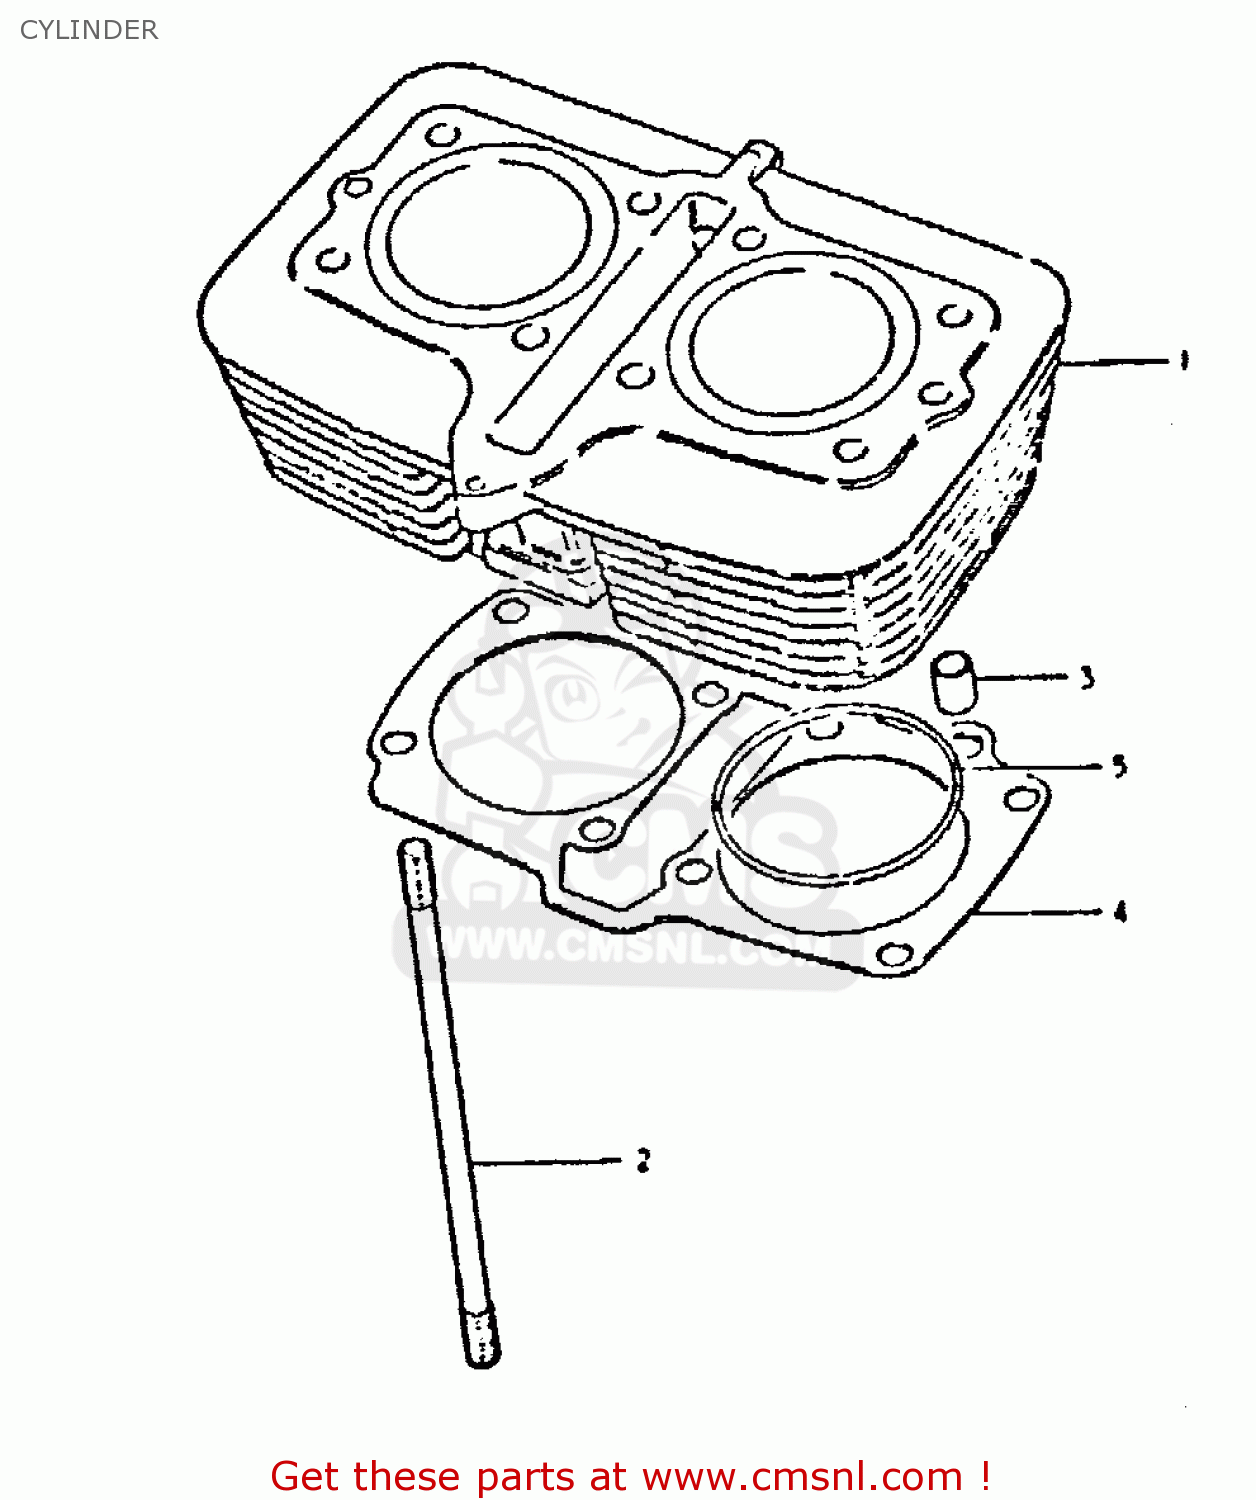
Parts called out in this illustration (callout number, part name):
1	CYLINDER
2	STUD
3	PIN
4	GASKET,CYLINDER (MCA)
5	O RING(D:2,ID:70)
